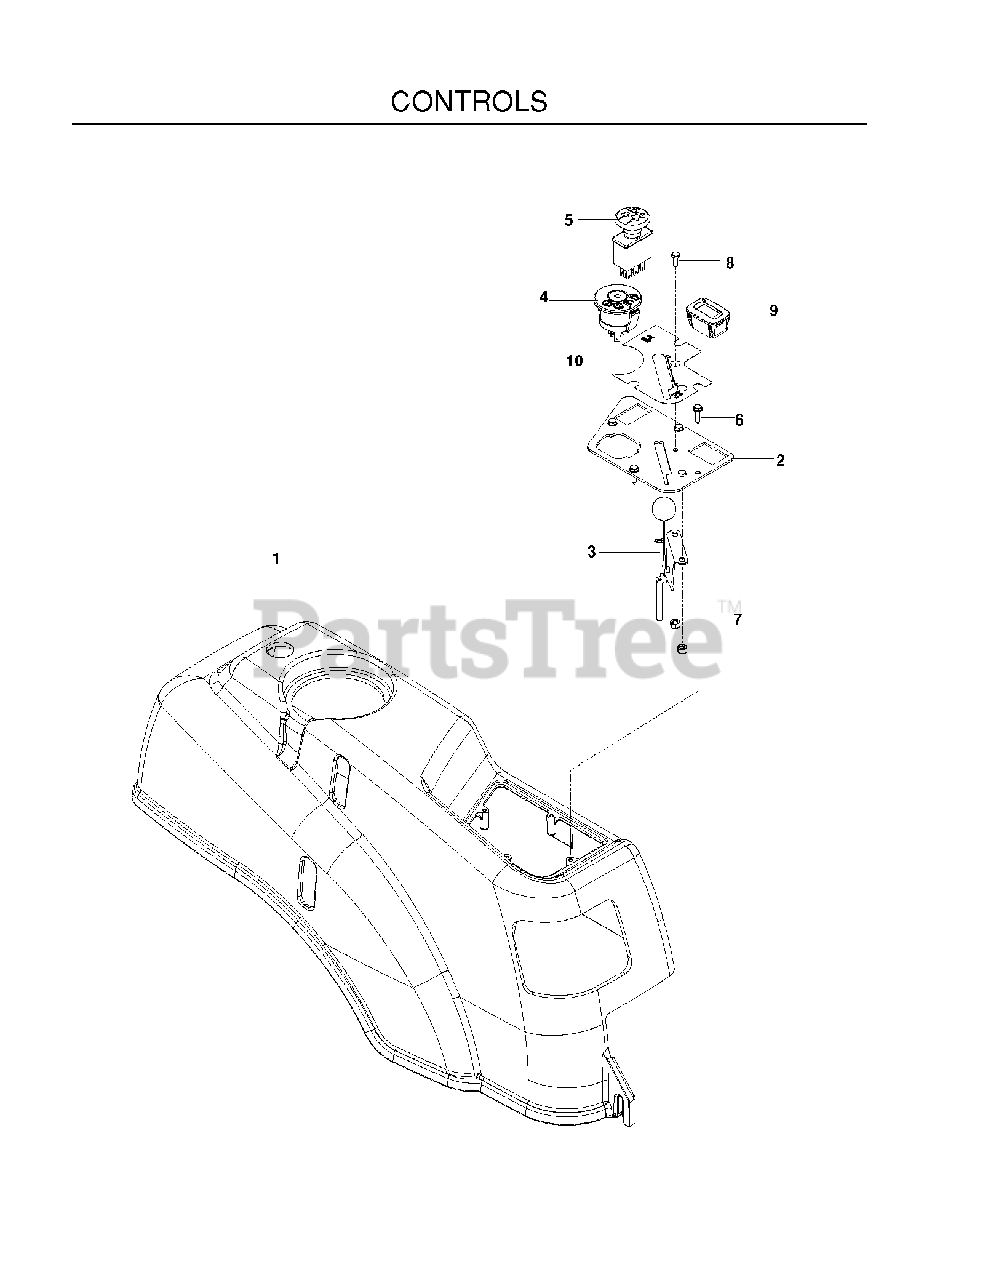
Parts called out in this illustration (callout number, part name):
1	FENDER, RT, BLK
2	CONSOLE.PLATE
3	CABLE, THROTTLE
4	IGNITION SWITCH
5	SWITCH, BLADE
6	HCS #10-24 X 1/2
7	NUT 10-24 NYLOC
8	SCR #10-12X3/4 HEX WAS HD ZD
9	HOUR METER
10	DECAL, CONTROL PANEL
